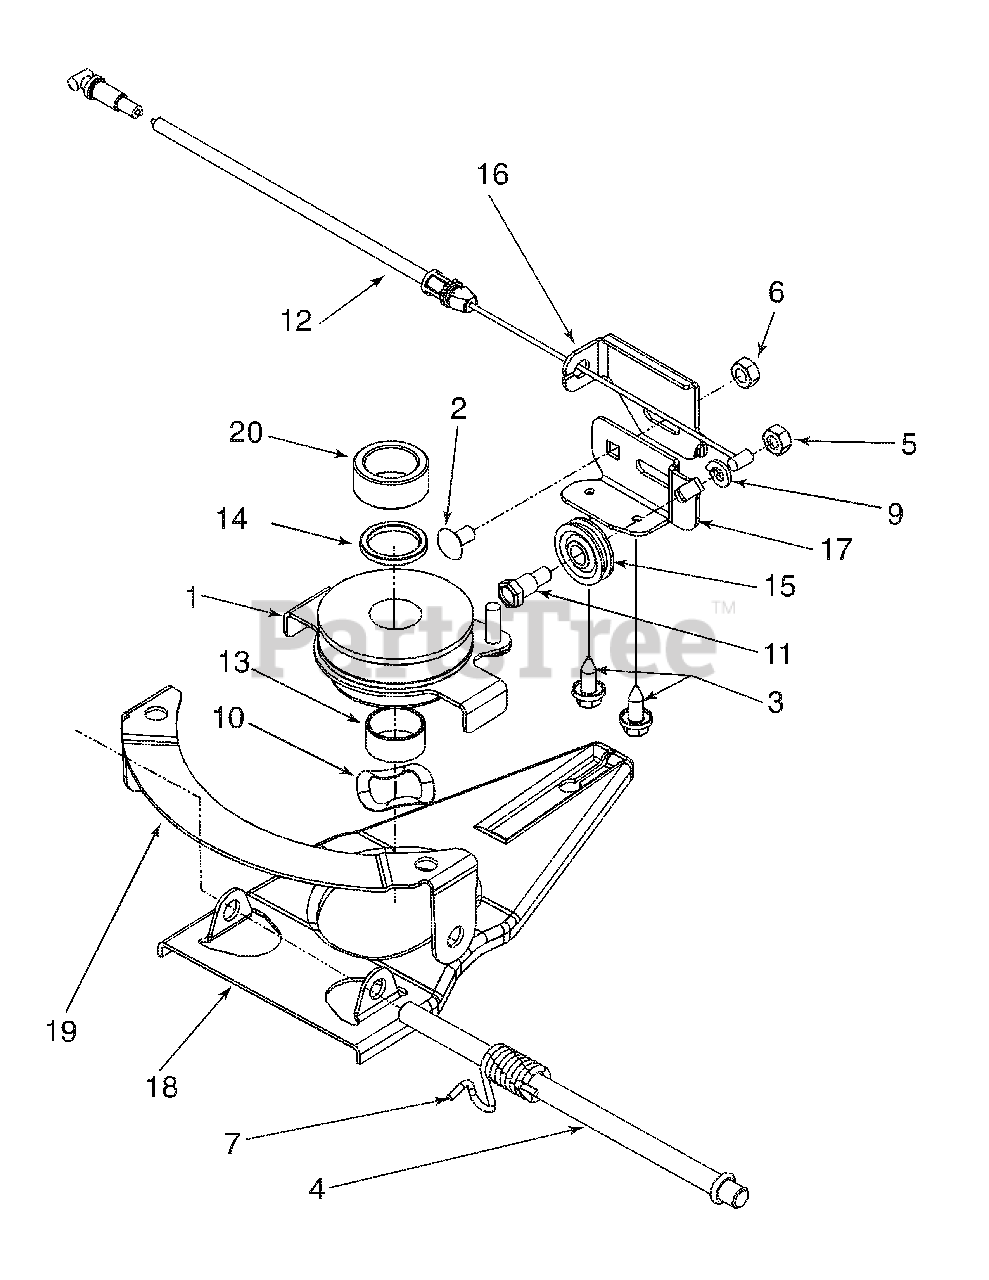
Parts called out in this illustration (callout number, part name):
1	Multi Speed Pulley Ass’y
2	Carriage Bolt 1/4-20 x .62\5" Lg. Gr. 2
3	Hex Wash HD. TT Tap Scr. 1/4-20 x .62
5	Hex Nut 1/4-28
6	Flanged Lock Nut 1/4-20 Gr. F Nylon
7	Torsion Spring LH
9	L-Wash 1/4 ID
10	Wave Washer .88 ID x 1.38 OD x .029
11	Hex Shld.Scr.1/4-28 x .375
12	Pulley Cable 53" Lg.
13	Sleeve Spacer .88 ID x 1.0 OD x .48
14	Sleeve Spacer .88 ID x 1.13 OD x .12
15	Cable Guide Roller
20	Sleeve Spacer .878 x 1.25 x .545
